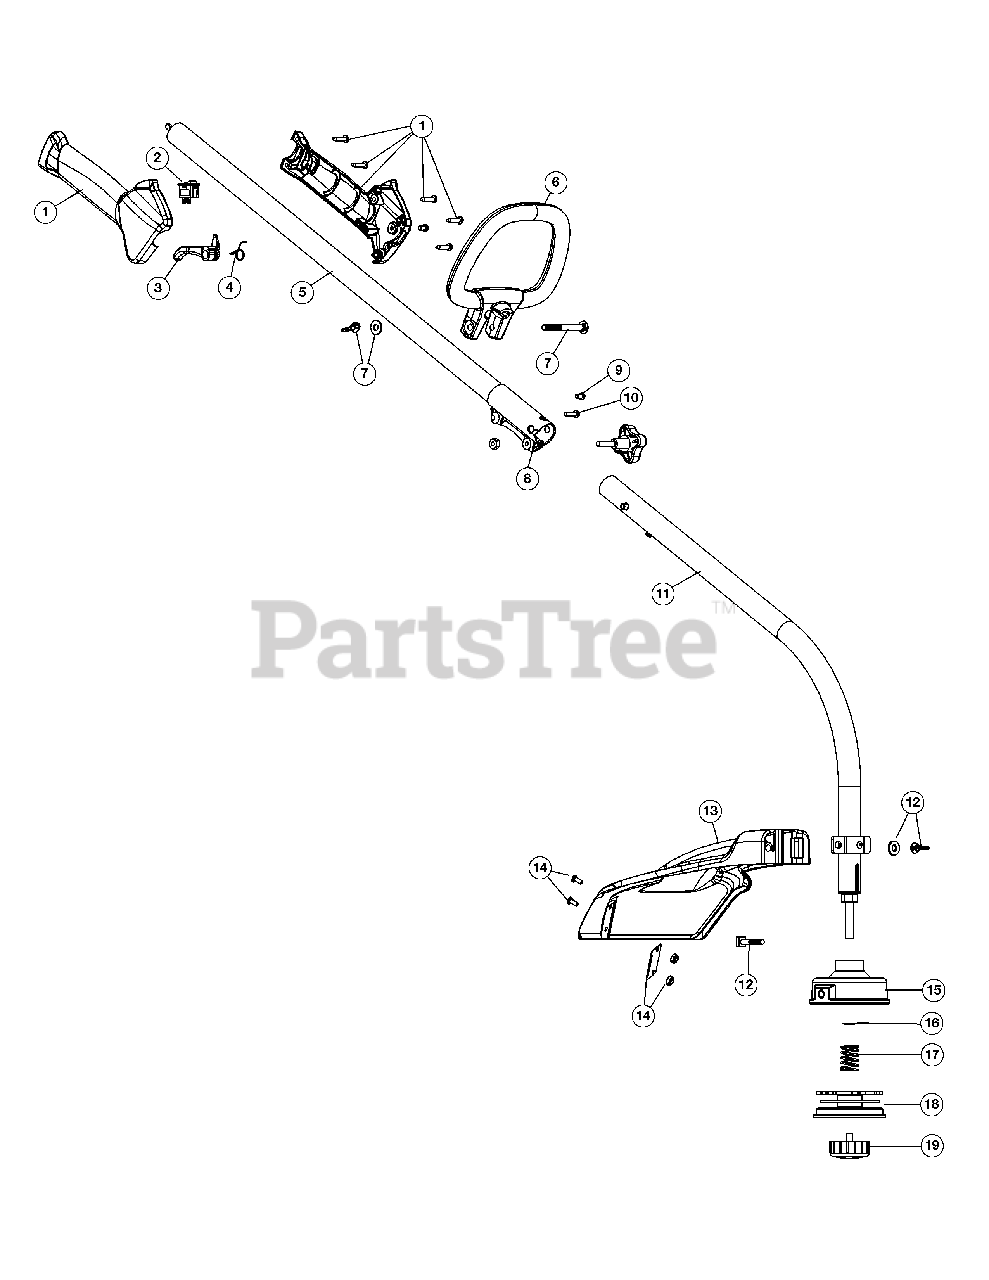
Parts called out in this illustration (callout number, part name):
1	Throttle Housing Assembly (Incl. 2-4)
3	Throttle Trigger
4	Throttle Trigger Spring
5	Upper Shaft Housing Assembly
6	D-Handle (Incl. 7)
7	D-Handle Hardware Assembly
8	Split Boom Coupler (Incl. 9-10)
9	Anti-Rotation Screw
11	Lower Shaft Housing Assembly
12	Shield Mounting Hardware
13	Shield Assembly (Incl. 16)
14	Blade Assembly
15	Outer Spool Assembly (Incl. 18)
16	Retainer
18	Inner Reel
19	Bump Head Knob Assembly
